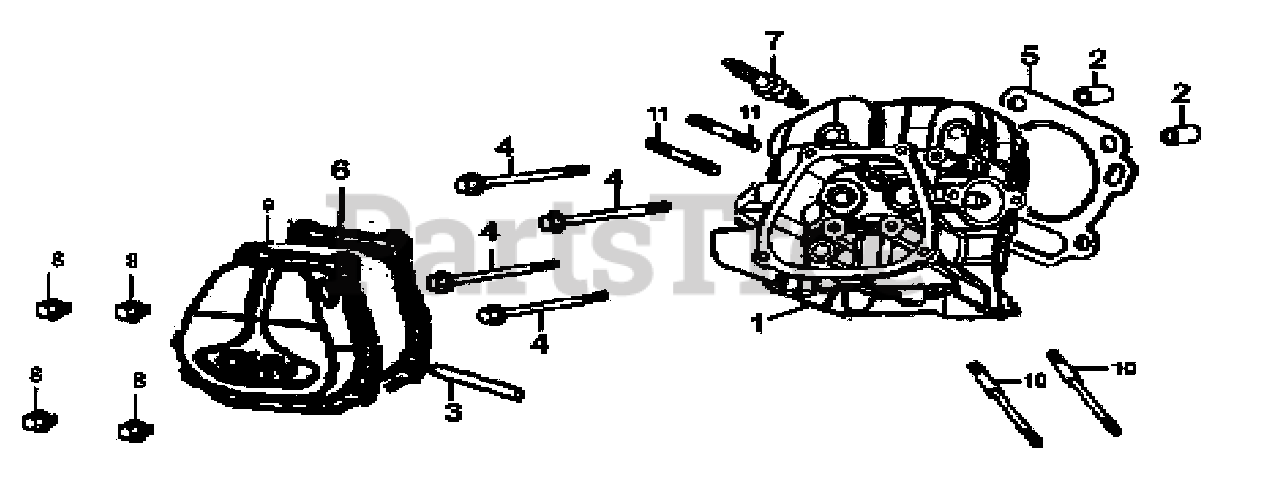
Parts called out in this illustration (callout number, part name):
1	HEAD COMP., CYLINDER
2	PIN, DOWEL
3	TUBE, BREATHER
4	BOLT, FLANGE
5	GASKET, CYLINDER
6	GASKET, HEAD COVER
7	PLUG, SPARK
8	BOLT, FLANGE
9	COVER COMP., HEAD
10	BOLT, STUD, INTAKE
11	BOLT, STUD, EXHAUST
